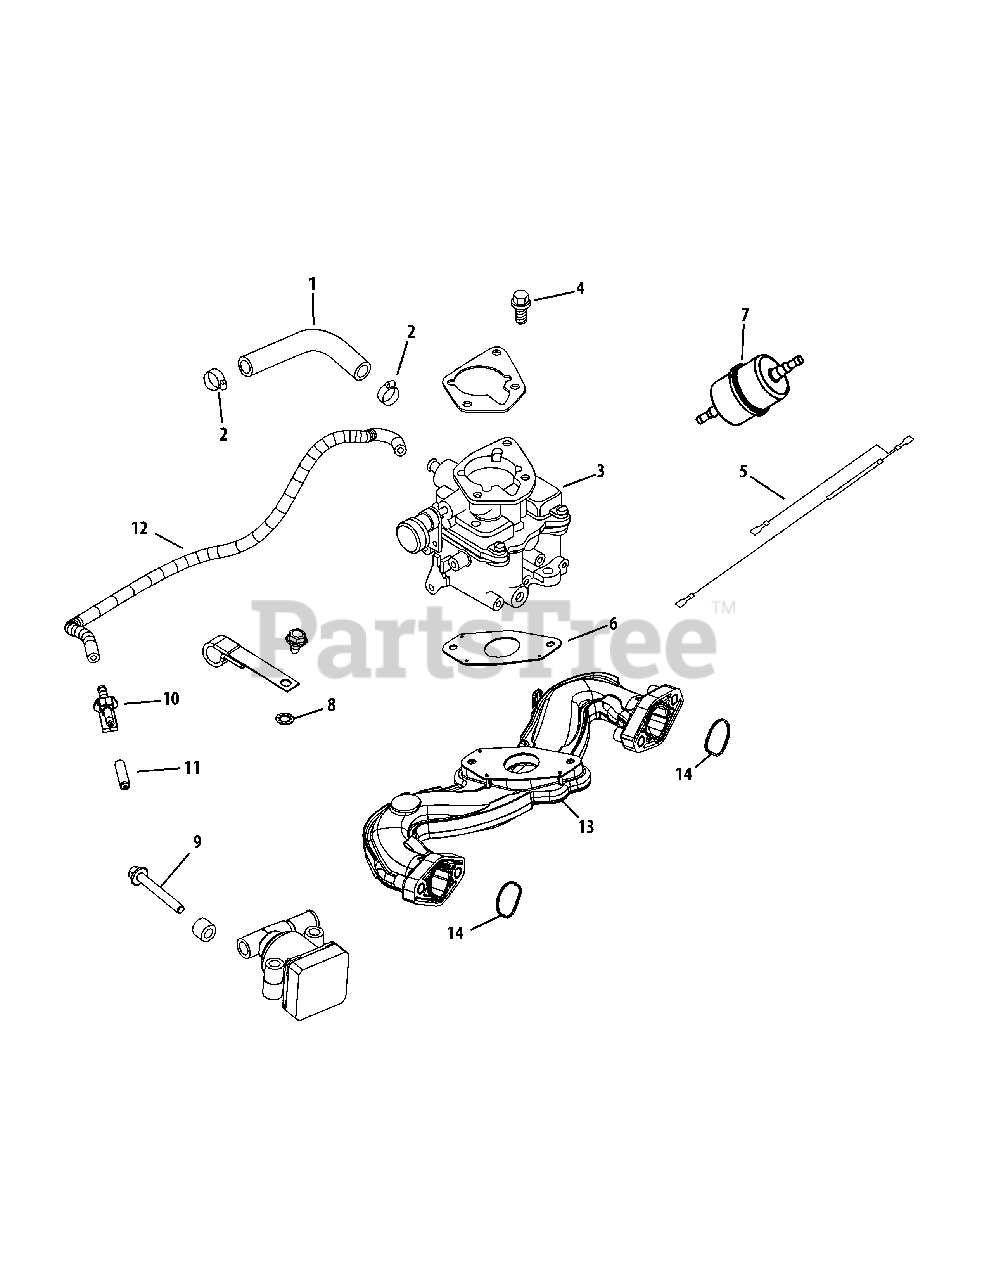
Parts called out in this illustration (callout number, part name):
1	Low Permeation Fuel Hose, 24"
3	Carburetor Kit w/ Gaskets
4	Flange Screw, M6 x 1.0 x 25
5	Internal Tooth Lock Washer, 1/4
6	Carburetor Gasket
7	Fuel Filter
9	Flange Screw, M6 x 1.0 x 40
10	Evaporative Connector
12	Evaporative Hose, 20"
13	Intake Manifold Kit
14	Intake Port O-Ring
